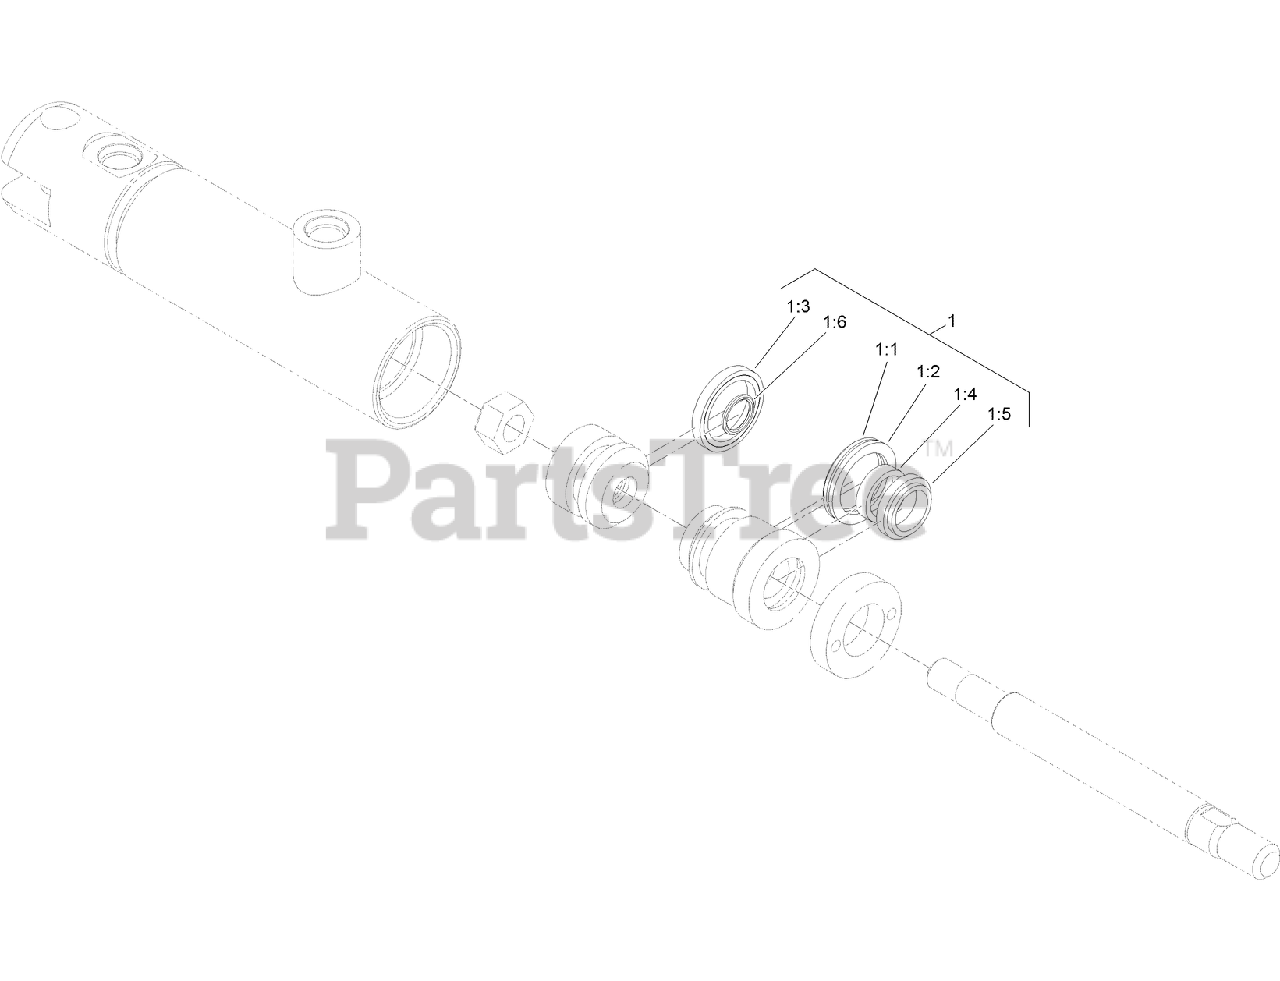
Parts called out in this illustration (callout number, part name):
1	SEAL KIT
1:1	Deck ASM
1:2	Deck ASM
1:3	SEAL-P S P
1:4	SEAL-B S
1:5	Deck ASM
1:6	Deck ASM
